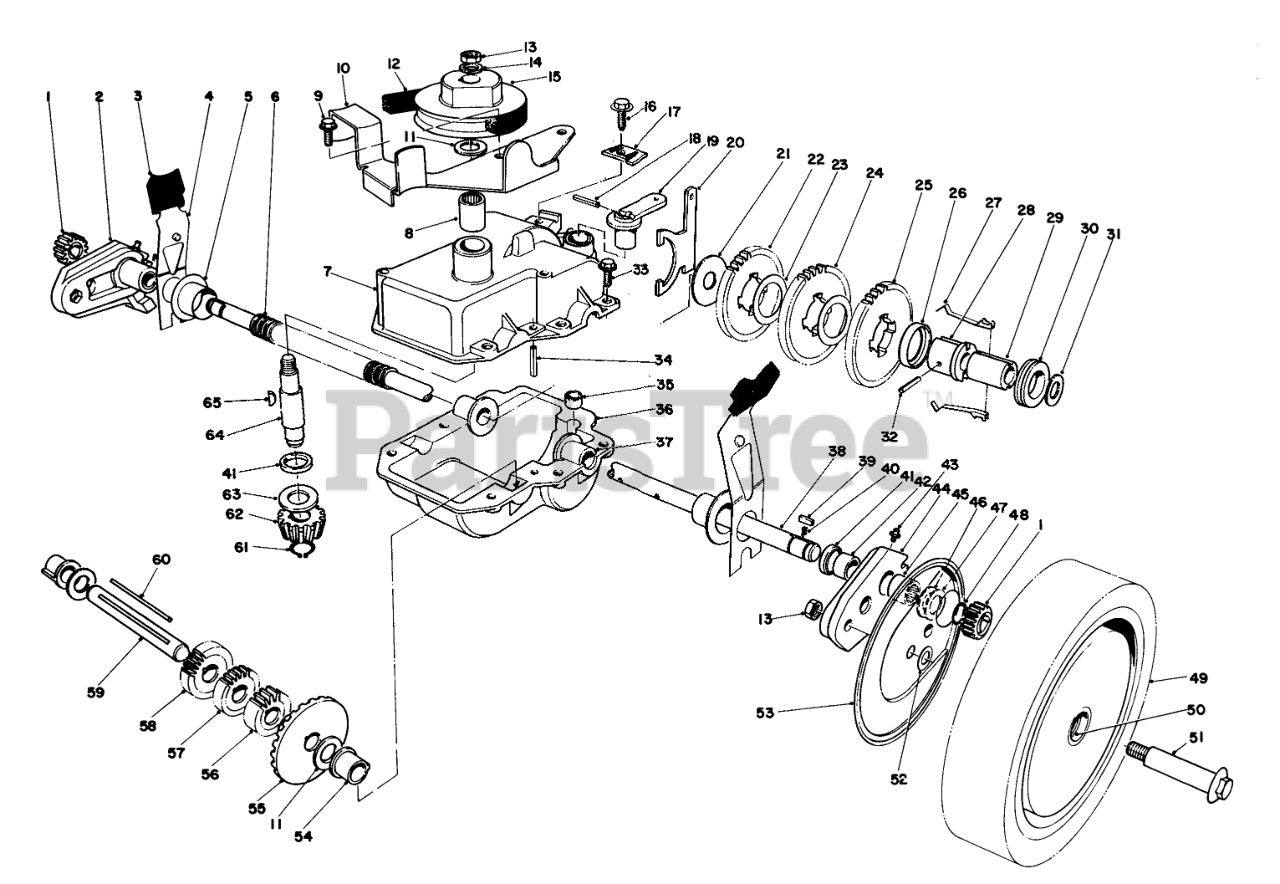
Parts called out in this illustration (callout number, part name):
1	GEAR-PINION
2	Pivot Arm R.H. (Incl. Ref. #40-43)
3	KNOB-ARM
4	SPRING ARM ASM SP
5	CAP-END
6	CONDUIT-CONVOLUTED, SPLIT
7	Case-Upper
8	BEARING
9	SCREW
10	Bracket-Belt Guide
11	WASHER-THRUST
12	V-BELT
13	Nut
14	WASHER-FLAT
15	PULLEY
16	SCREW-HWHTF
17	Cable Clamp
18	PIN-COIL
19	LEVER-SHIFT
20	Shift Yoke
21	WASHER
22	GEAR-38T
23	WASHER
24	GEAR-42T
26	KEY RETAINER
27	Key
28	Body-Sleeve
29	SLEEVE
30	COLLAR-SHIFT
31	WASHER-PLAIN
32	PIN-ROLL
33	SCREW-HWH, THREAD ROLL
34	ROLL PIN 3/16 X 1 IN
35	BUSHING-YOKE
36	LOWER GEAR CASE CAST
37	Bushing-Output Shaft
38	Output Shaft
39	KEY RECTANGULAR
40	SPRING-COMPRESSION
42	BUSHING
43	FITTING-GREASE
44	Pivot Arm L.H. (Incl. Ref. #40-43)
45	BEARING-ROLLER
46	Washer
47	THRUST WASHER
48	RING-RETAINING
49	Wheel, Tire & Gear Assembly
51	Wheel Bolt
52	WASHER
53	WHEEL COVER
54	BUSHING
55	BEVEL GEAR
56	GEAR-12T
57	GEAR-14T
58	GEAR-18T
59	INTERMEDIATE SHAFT
60	Key Square
61	RING-RETAINING
62	PINION-BEVEL
63	WASHER-THRUST
64	INPUT SHAFT
65	KEY-WOODRUFF
